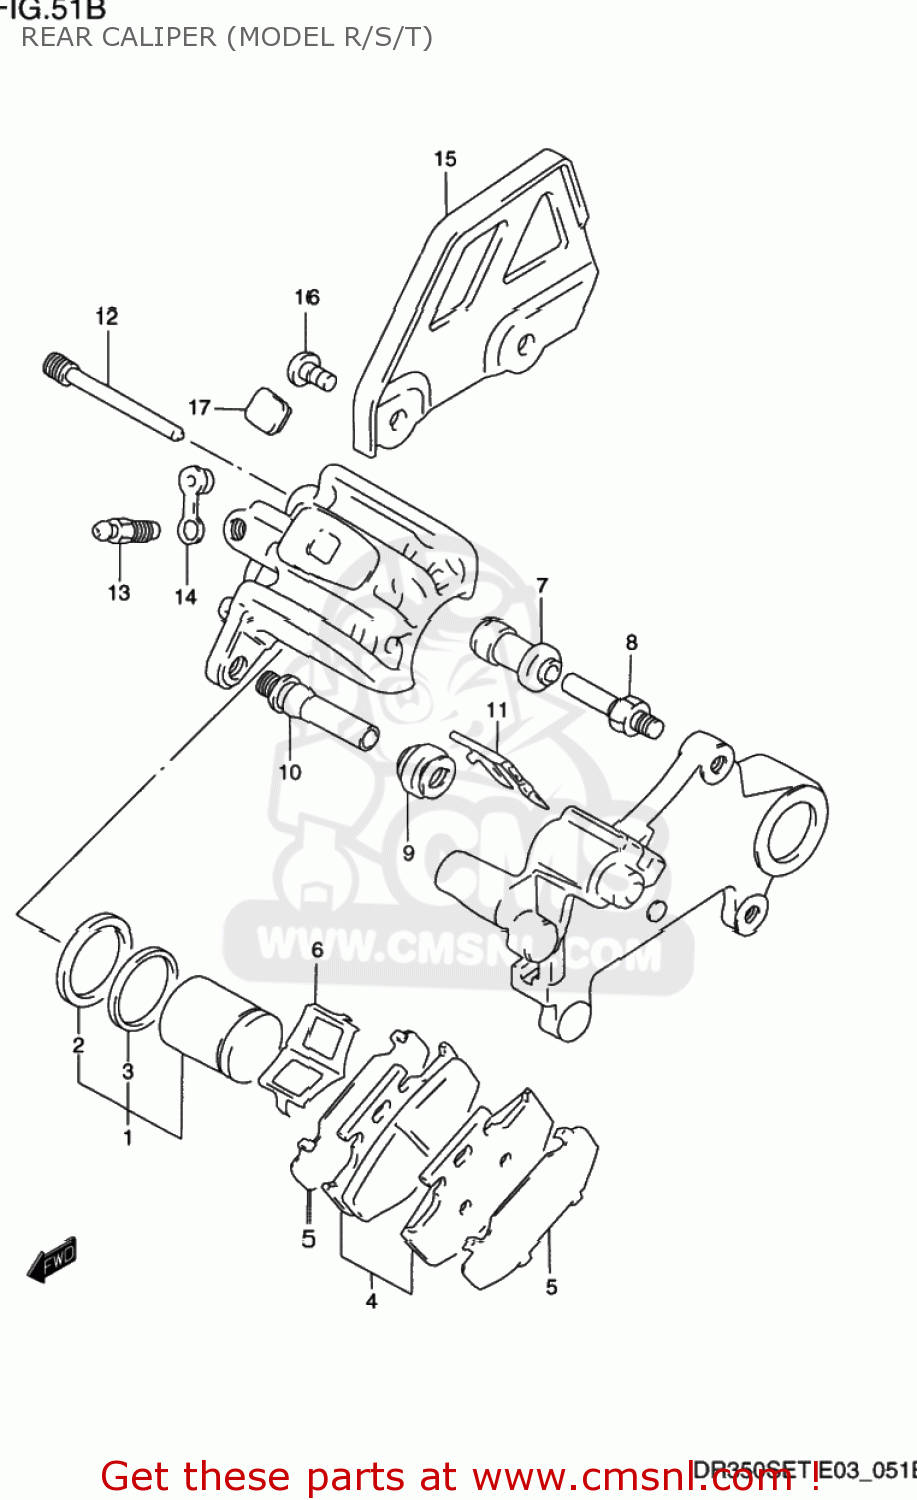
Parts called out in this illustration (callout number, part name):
1	PISTON SET
2	SEAL,PISTON
3	SEAL
4	PAD SET (NAS)
5	SHIM
6	SPRING,PAD
7	BOOT
8	PIN,BOLT
9	BOOT
10	PIN
11	RETAINER,BRACKET
12	PIN,HANGER
13	BLEEDER
14	CAP,BLEEDER
15	GUARD,RR CALIPER
16	SCREW 6X12
17	COVER,RR CALIPER BODY
